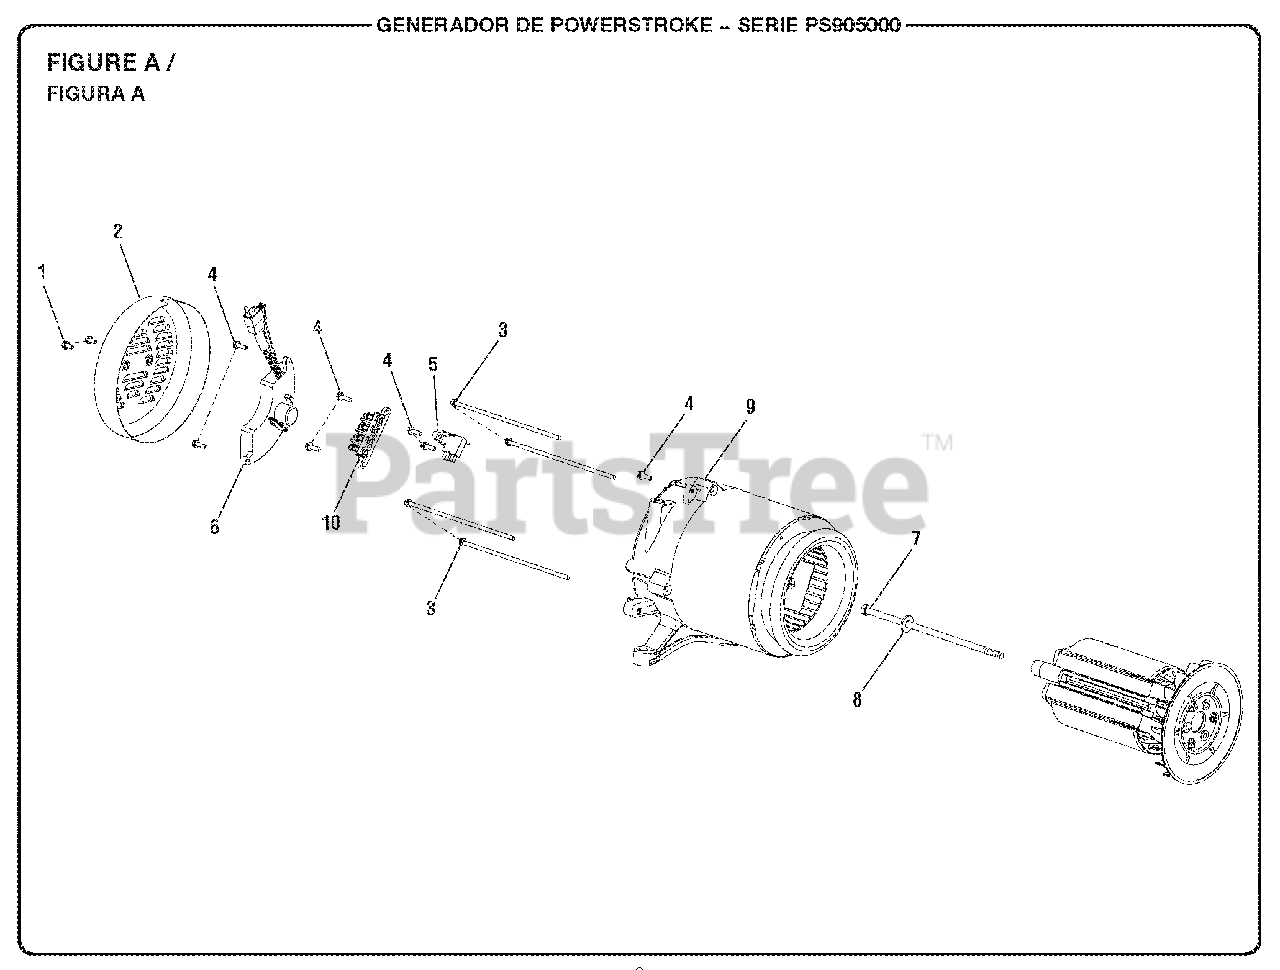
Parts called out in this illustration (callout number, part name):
1	Bolt (M5 x 10 mm, Hex Hd.)
2	Brush Cover
3	Bolt (1/4-20 x 7 in., Hex Hd.)
4	Bolt (M5 x 16 mm, Hex Hd.)
5	Brush Assembly Kit
6	Automatic Voltage Regulator (5000 Watt)
7	Washer (5/16 in.)
8	Bolt (Rotor)
9	Bearing Support
10	Terminal Block Assembly
